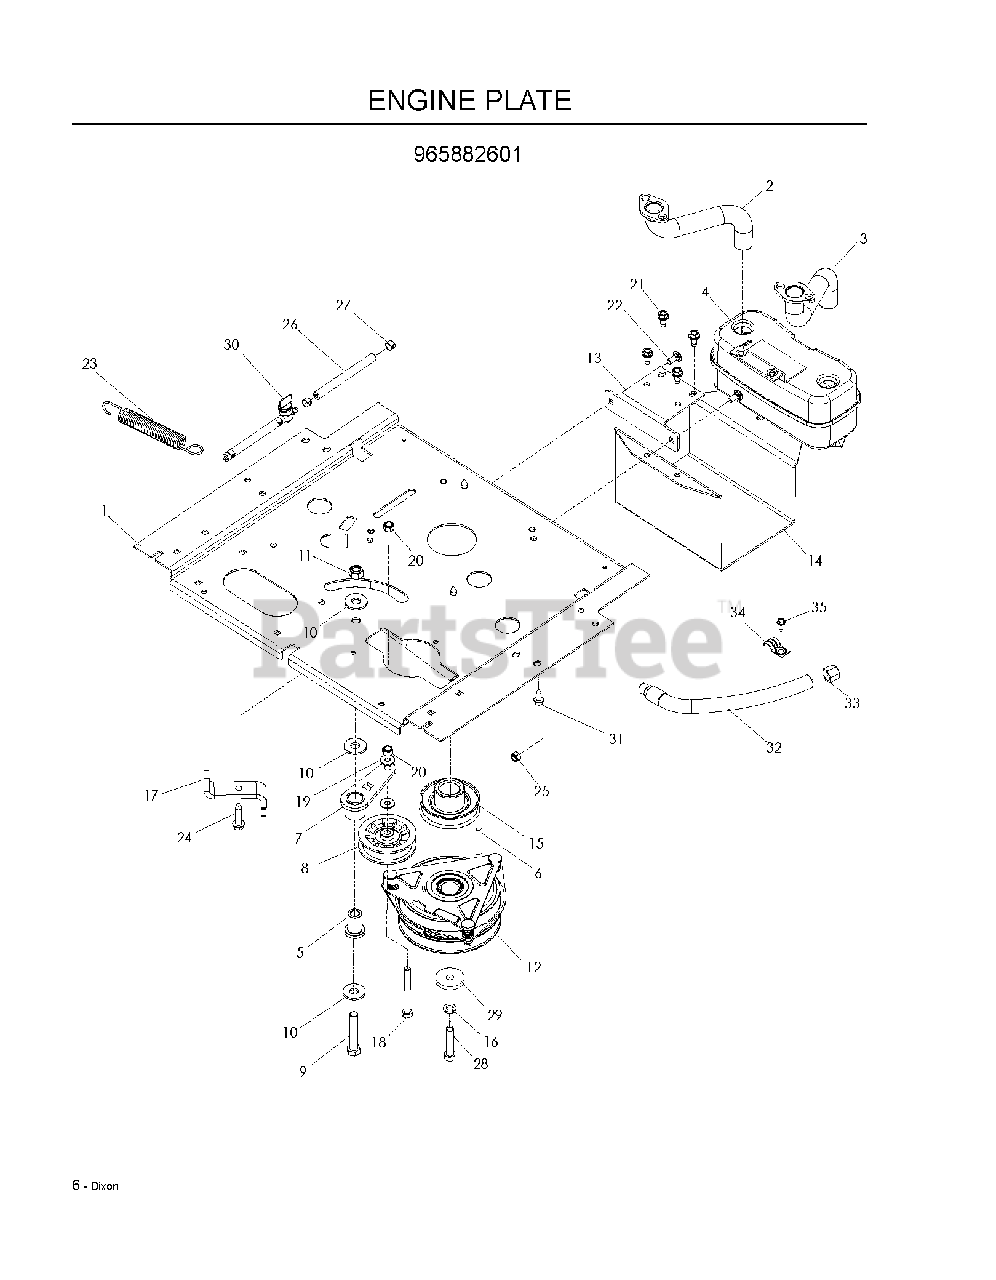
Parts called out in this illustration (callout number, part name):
1	PLATE, ENGINE, BLACK
2	RP.PIPE-EXHAUST LH
3	RP.PIPE-EXHAUST RH
4	MUFFLER ASM TWIN
5	PIVOT, IDLER
6	KEY 1/4 SQ X 2
7	IDLER ARM WELDMENT
8	PULLEY, IDLER
9	HCS 1/2C X 2 3/4
10	WASH USS FLAT 1/2
11	NUT 1/2-13 HEX NYLOC ZD
12	CLUTCH, 150 FT/LBS
13	BRACKET, MUFFLER, BLACK
14	GUARD, MUFFLER, BLACK
15	PULLEY, DRIVE
16	WASHER 7/16 LOCK
17	STOP, CLUTCH, OGURA, BLK
18	HCS 3/8-16X3 1/2 GR5
19	WASHER 5/16 FLAT
20	NUT 3/8-16 NYLOC
21	BOLT 5/16-18 X 3/4
22	BOLT 5/16C X 3/4" CARRIAGE
23	SPRING, DECK DRIVE
24	BOLT 3/8-16 X 1 1/2 ZINC CLEAR
25	5/16-18 NYLOC FLANGE NUT
26	FUEL LINE 5"
27	HOSE CLAMP
28	HCS 7/16-20 X 2 G8 ZN
29	SPINDLE WASHER
30	FUEL VALVE
31	HHFS 3/8-16 X 1.0 THD FORMING
32	OIL DRAIN HOSE
33	DRAIN CAP
35	SCREW 1/4 X 5/8
